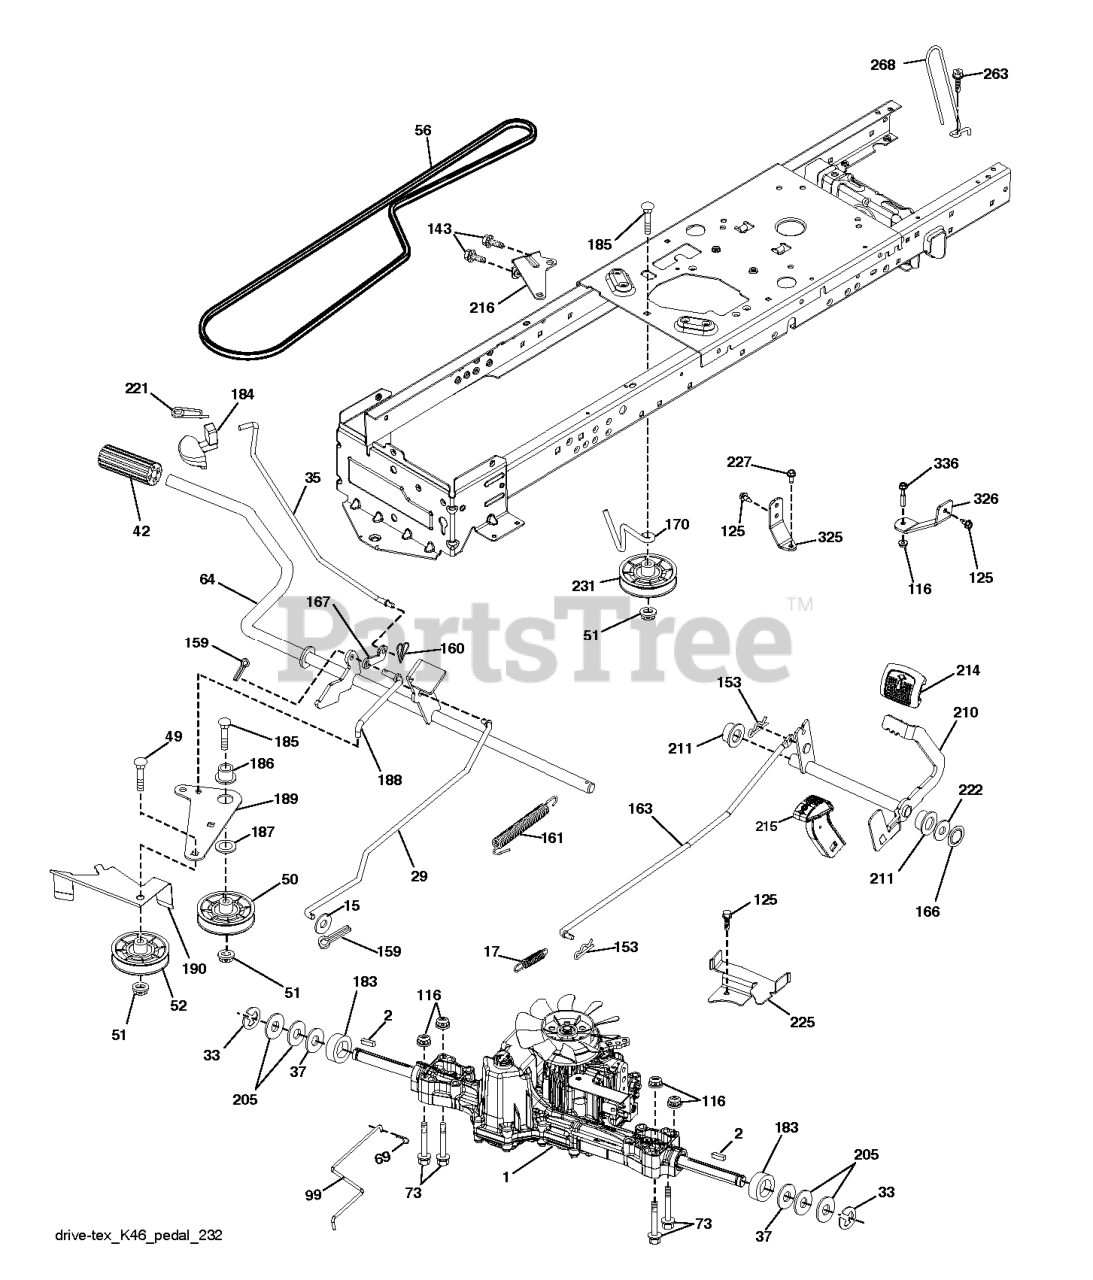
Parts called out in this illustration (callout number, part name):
2	SQUARE KEY
15	WASHER
17	SPRING.BRAKE.K46.GREEN
29	ROD.BRAKE.K46
35	ROD.CNTRL.PARK.PREDATOR.LT.TEX
37	WASHER.HARDENED
42	PEDAL COVER
50	IDLER.FLAT.910.OFFSET
51	NUT LOCK FLG 3/8-16 UNC
52	IDLER.V-GROOVE.910.OFFSET
64	SHAFT.ASM.PEDAL.BRK.CNTR
69	HAIRPIN.SOFT.ZINC.059X1.125
99	ARM.PIVOTING.TCRD.GEN2.5.BAGGE
116	NUT LOCK HEX FLANGE 5/16-18
125	SCREW
143	SCR 5/16-18 X 1/2 SELFTAP ZN
153	RETAINER M
159	COTTER PIN
160	RETAINER CLIP
161	SPRING, RETURN LT
163	ROD.CONTROL.K57R.K46
166	NUT.PUSH.625
167	LATCH.BRAKE.SPRING
170	KEEPER.CENTER SPAN.1.688
183	SPACER AXLE
184	HANDLE.PARKNG BRK.PRED.LT.428
186	SPACER.RETAINER
187	WASHER 12/32X2X10GA
188	LINK.CLUTCH.GROUND DRIVE.LONG
189	BELLCRANK.GROUND.DRIVE.TEX.
190	KEEPER.BELLCRANK.DRIVE
210	ROCKER.ASM.PEDAL.CONTR
211	BEARING.NYLON
214	PEDAL.FORWARD.PAD.TEX
215	PEDAL.COVER.REVERSE.CRD.X428BK
216	BRACKET.PULLEY.IDLER.W/TEX
221	RETAINER.SPRING.CLIP.H
222	WASHER 21/32 X 1-1/4 X 10 GA.
225	KEEPER.BELT.TRANSAXLE.K46
227	SCREW.THDROL.5/16-18X3/4.TTY
231	IDLER.V-GROOVE.1.688.OFFSET
263	SCREW, 3/8-16X3/4
325	BRCKT.PNT.TRQ.STP.46.18TIRE.RH
326	TORQUE.STRAP.K46.LT.LH
336	BOLT.5/16-18X1-3/4.FLANGED.HEX
